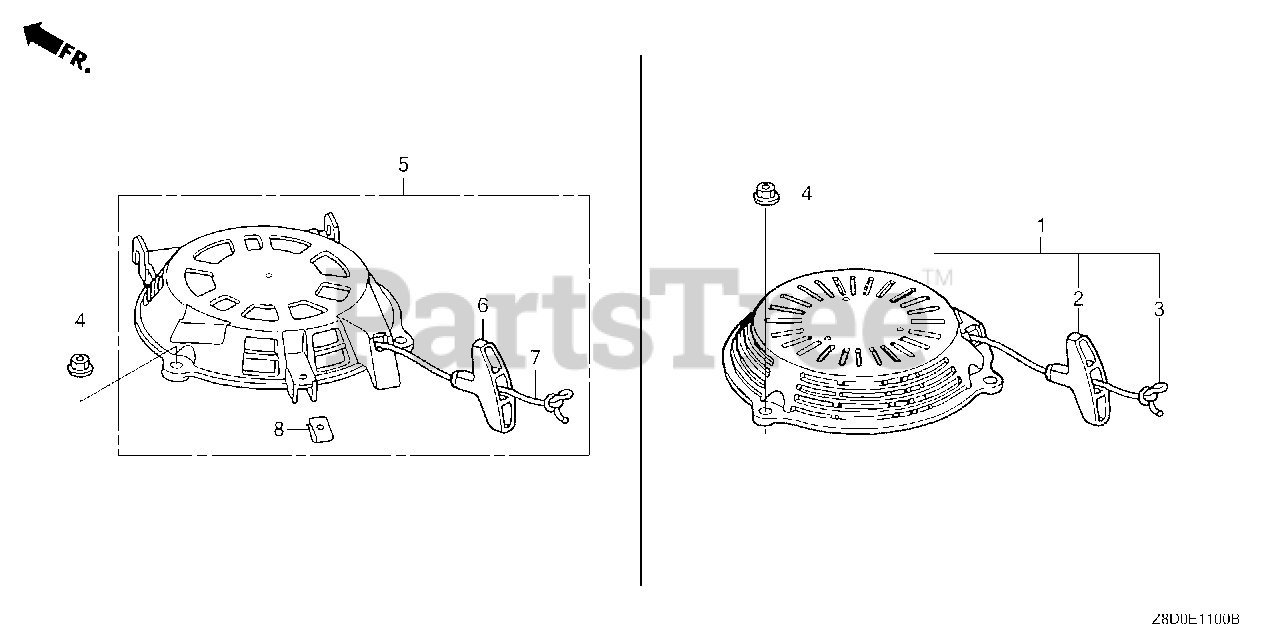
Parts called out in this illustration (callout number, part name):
1	STARTER ASSY., RECOIL *NH1* (LONG ROPE) (BLACK)
2	KNOB, RECOIL STARTER
3	ROPE, RECOIL STARTER (LONG TYPE)
4	NUT, FLANGE (6MM)
